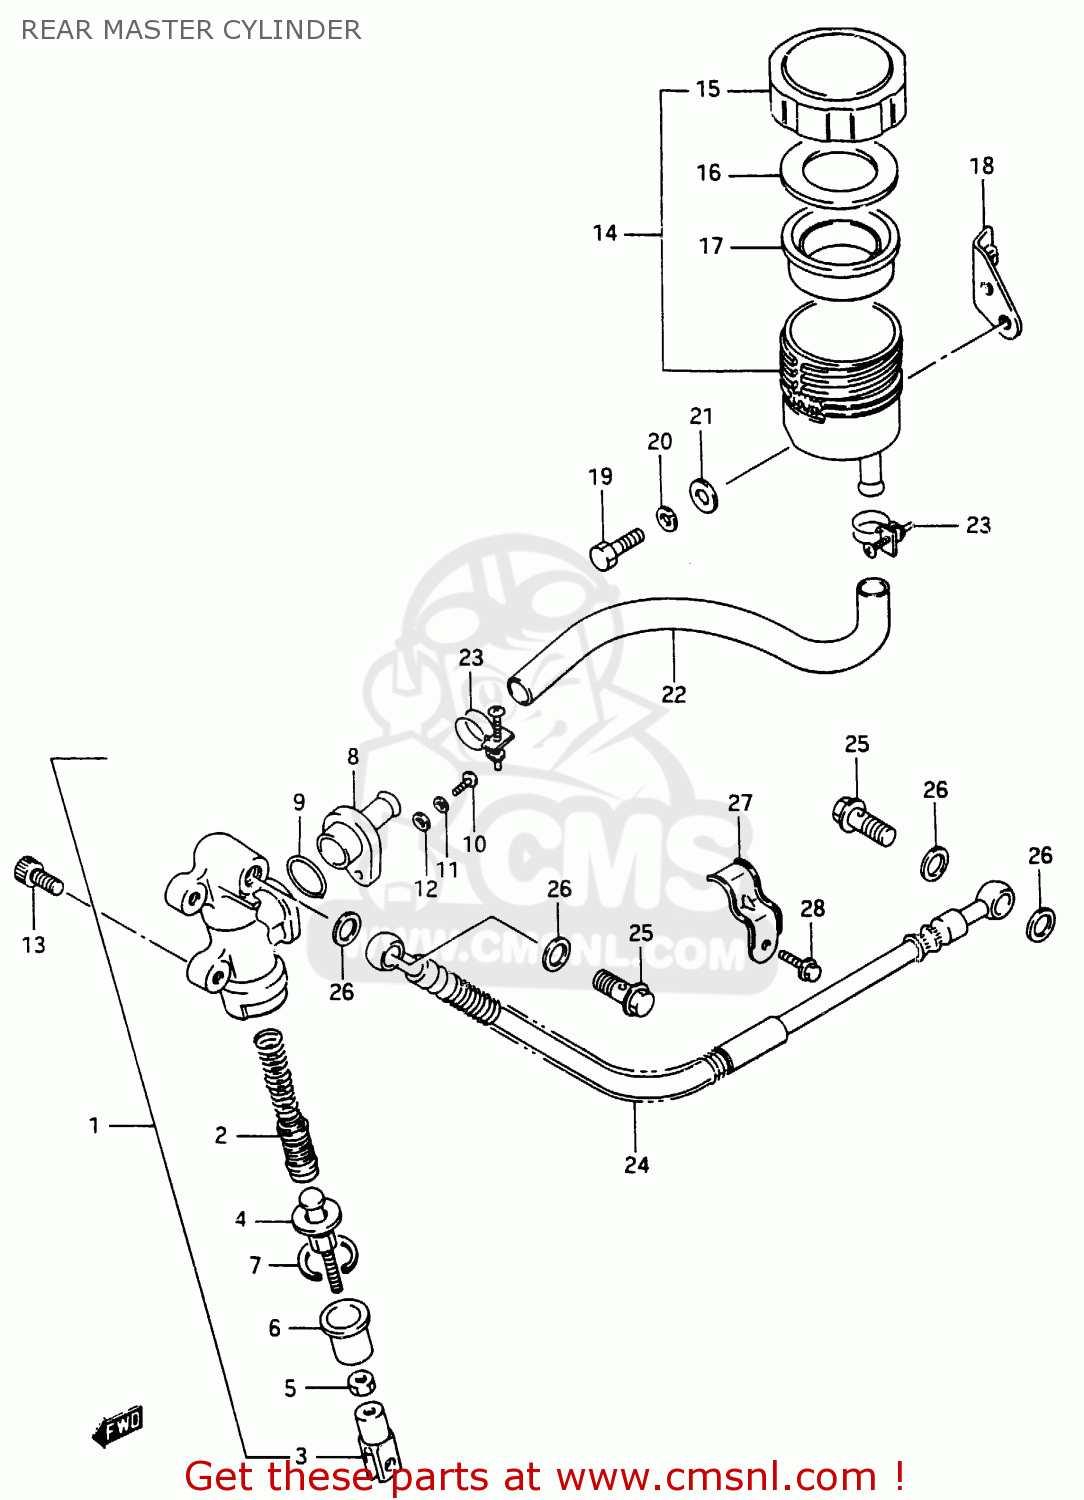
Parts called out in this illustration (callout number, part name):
1	CYLINDER ASSY,RR MASTER
2	PISTON/CUP SET
3	YOKE
4	ROD,PUSH
5	NUT,MASTER CYLINDER
6	BOOT
7	CIRCLIP
8	CONNECTOR
9	O RING
10	SCREW
11	LOCK WASHER
12	WASHER
13	BOLT
14	TANK ASSEMBLY,RESERVOIR
15	CAP
16	PLATE,DIAPHRAGM
17	DIAPHRAGM
18	PLATE, RESERVOIR TANK
19	BOLT
20	WASHER,LOCK
21	WASHER
22	HOSE, RESERVOIR TANK
23	CLAMP
24	HOSE, REAR BRAKE
25	BOLT UNION
26	WASHER(10X15X1.5)
27	GUIDE,REAR BRAKE HOSE
28	BOLT
